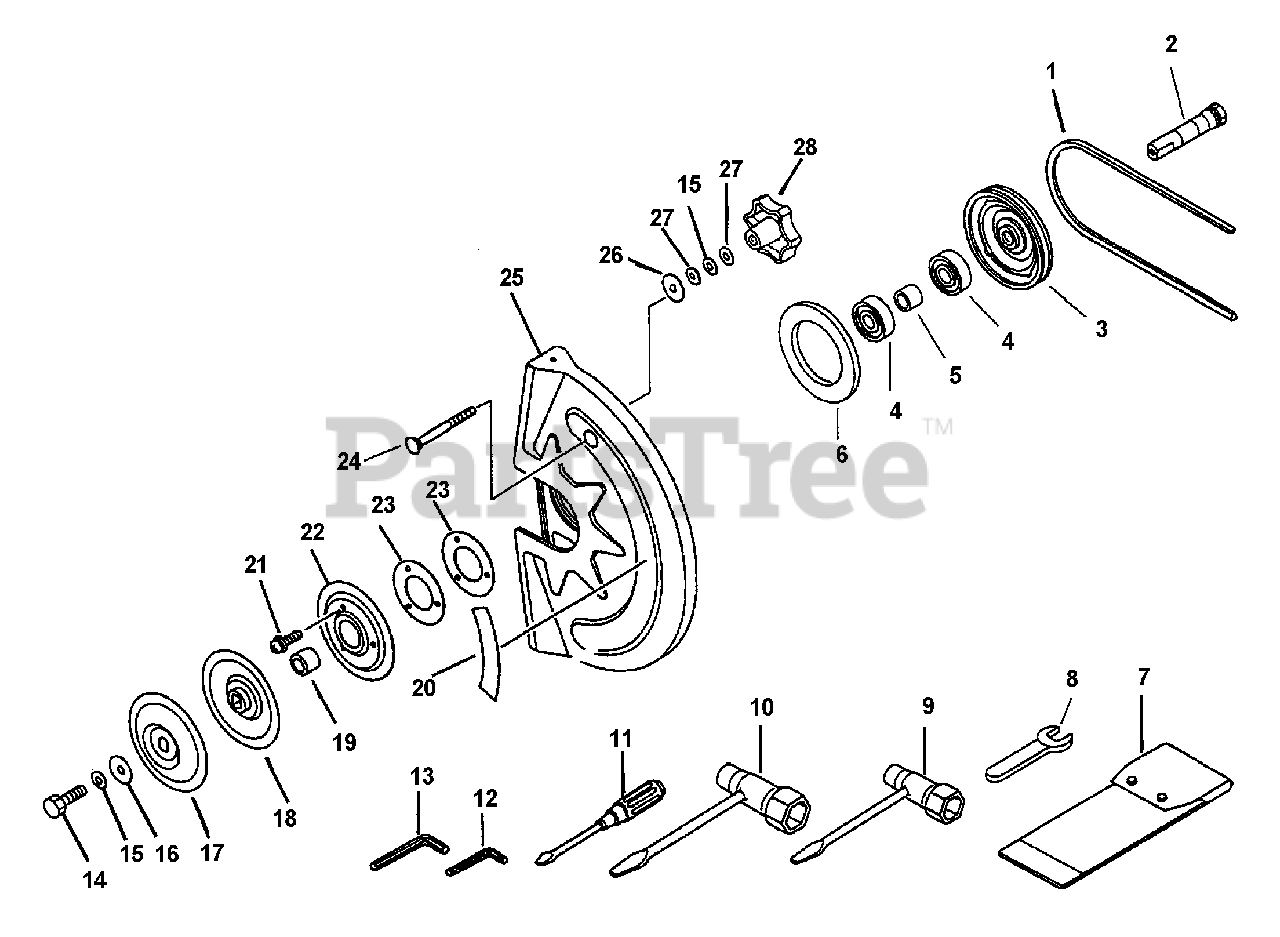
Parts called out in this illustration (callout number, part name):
4	BEARING, BALL 6203
5	SPACER
7	BAG, TOOL
8	WRENCH, OPEN END 10 MM
9	T-WRENCH 13×19×180
10	WRENCH, T 17×19 MM
11	SCREWDRIVER, SLOTTED
12	WRENCH, ALLEN 3 MM
13	WRENCH, ALLEN 4 MM
15	WASHER, SPRING 10
17	FLANGE, CUTTER
18	FLANGE, CUTTER
20	LABEL, CAUTION
21	SCREW 4×10
22	PLATE
25	COVER, BLADE
27	WASHER 10.5×18×1.6
